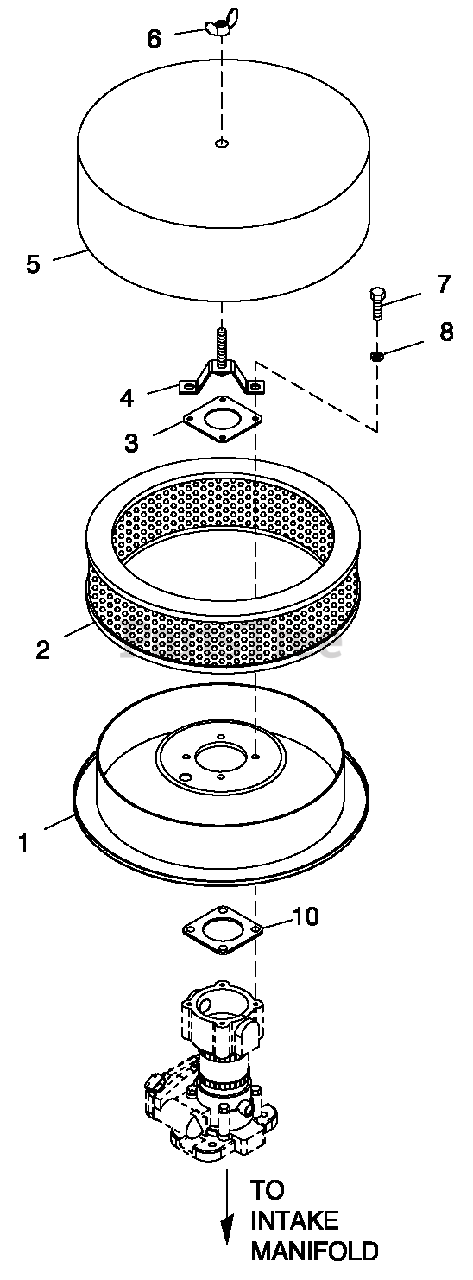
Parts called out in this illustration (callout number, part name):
1	BOTTOM PLATE, AIR CLEANER 3.9L
2	ELEMENT AIR FILTER
3	HOLDER VENTURI
4	HOLD DOWN AIR CLEANER
5	PLATE, AIR CLEANER TOP 3.9L
6	NUT WING 1/4-20 NYLK
7	SCREW HHC M5-0.8 X 16 G8.8
8	WASHER LOCK M5
10	GASKET BOSCH 32 & 40
